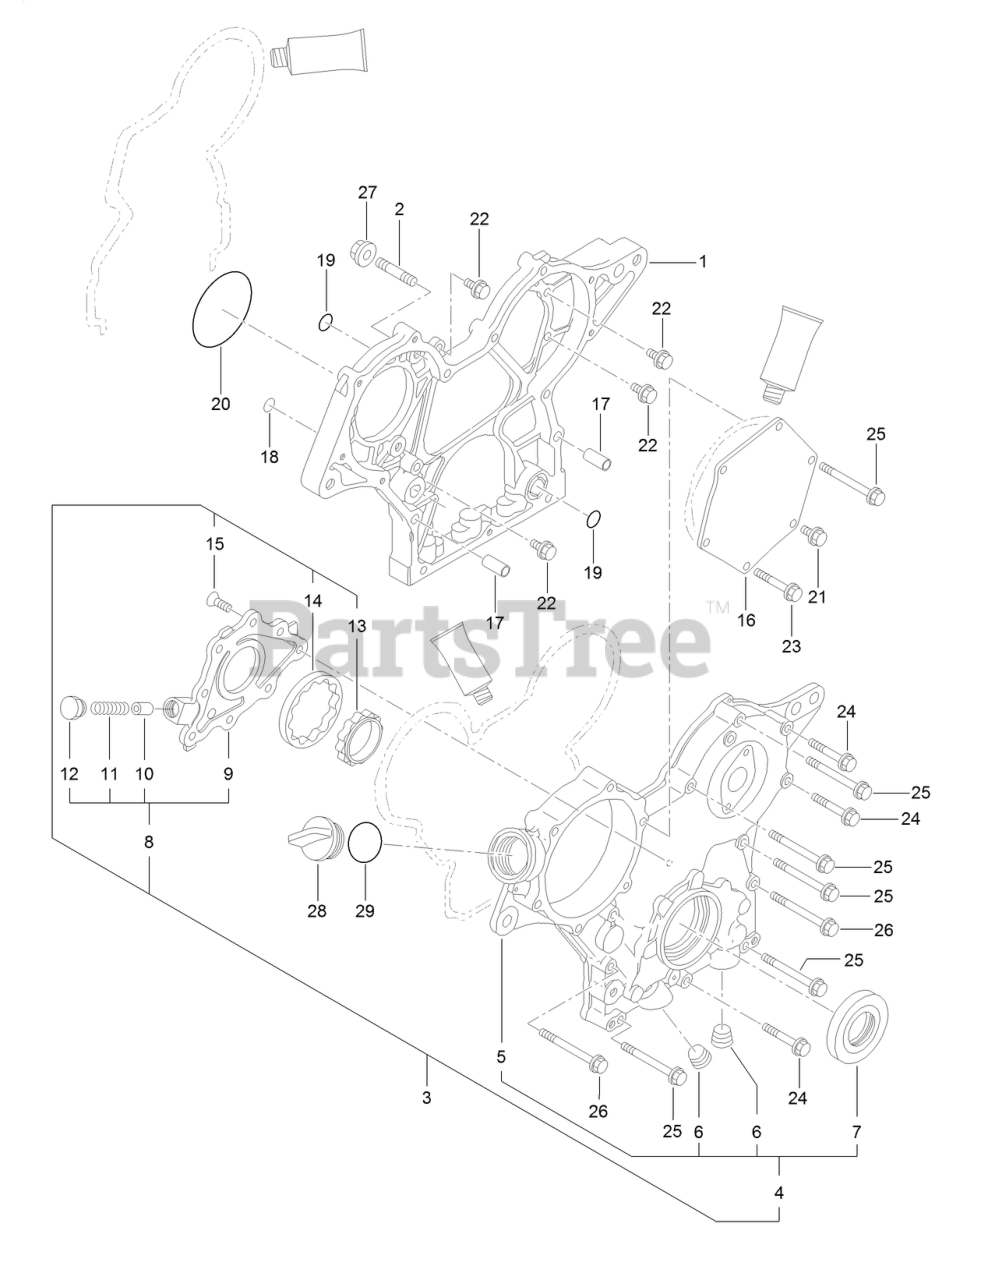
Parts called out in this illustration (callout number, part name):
1	CASE-GEAR
2	BOLT-STUD
3	COVER ASM-GEAR CASE
4	COVER ASSY-GEAR CASE
5	COVER-GEAR CASE
7	SEAL-OIL
8	COVER ASM
9	COVER-PUMP
10	VALVE-RELIEF
13	ROTOR-INNER
14	ROTOR-OUTER
16	COVER-PUMP
17	PIPE-DOWEL
28	COVER-FILLER
